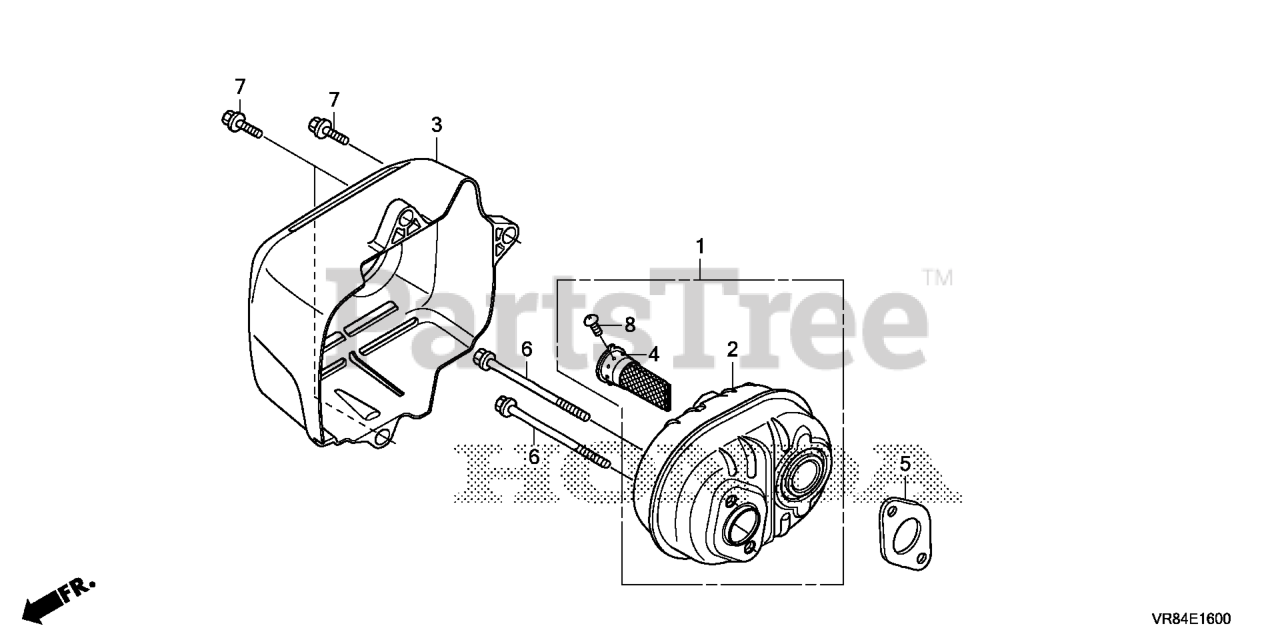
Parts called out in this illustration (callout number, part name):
1	MUFFLER ASSY. (ARRESTER)
3	PROTECTOR, MUFFLER
4	ARRESTER, SPARK
5	GASKET, MUFFLER
6	BOLT, FLANGE (6X79) (CT200)
7	BOLT, FLANGE (6X23)
8	SCREW, TAPPING (4X6) (TO INSTALL OPTIONAL SPARK ARRESTER)
